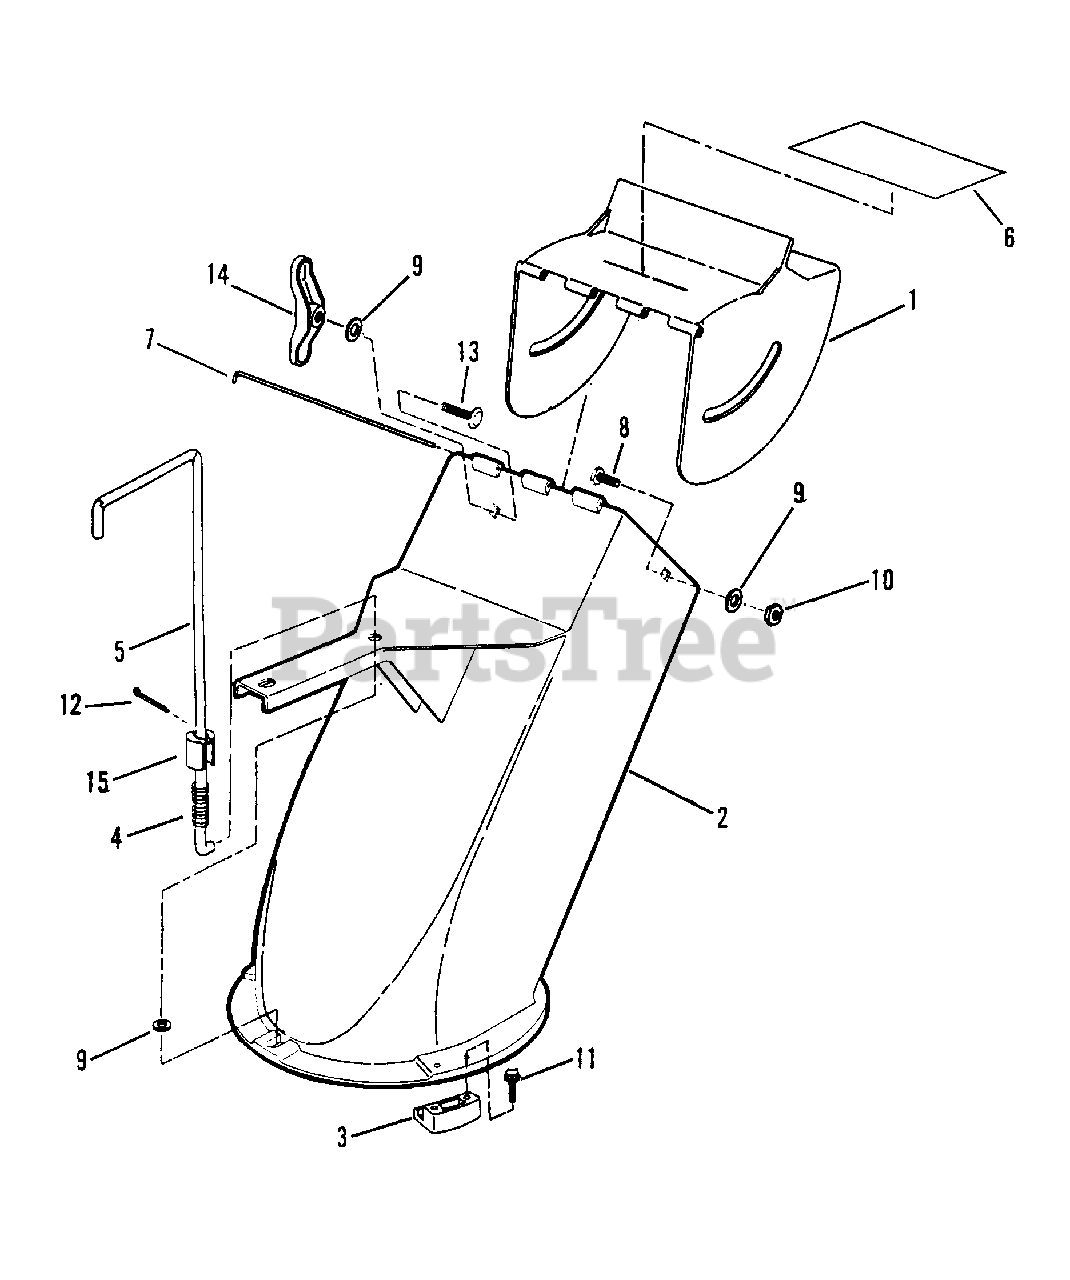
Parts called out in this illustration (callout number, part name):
1	DEFLECTOR, Discharge
3	RETAINER, Chute to Housing
4	SPRING, Release Rod
5	ROD, Release
6	DECAL, Danger
7	PIN, Wire Hinge
8	SCREW, 5/16-24 x 3/4" Hex Head Cap, Grade 5
9	WASHER, 5/16 Flat
10	NUT, 5/16-24 Hex Center Lock, Grade B
11	SCREW, #10-24 x 5/8" Hex Head Cap, Grade 5
12	PIN, 3/32 x 3/4" Cotter
13	BOLT, 5/16-18 x 3/4" Carriage, Grade 5
14	NUT, 5/16-18 Wing
15	STOP, Handle
